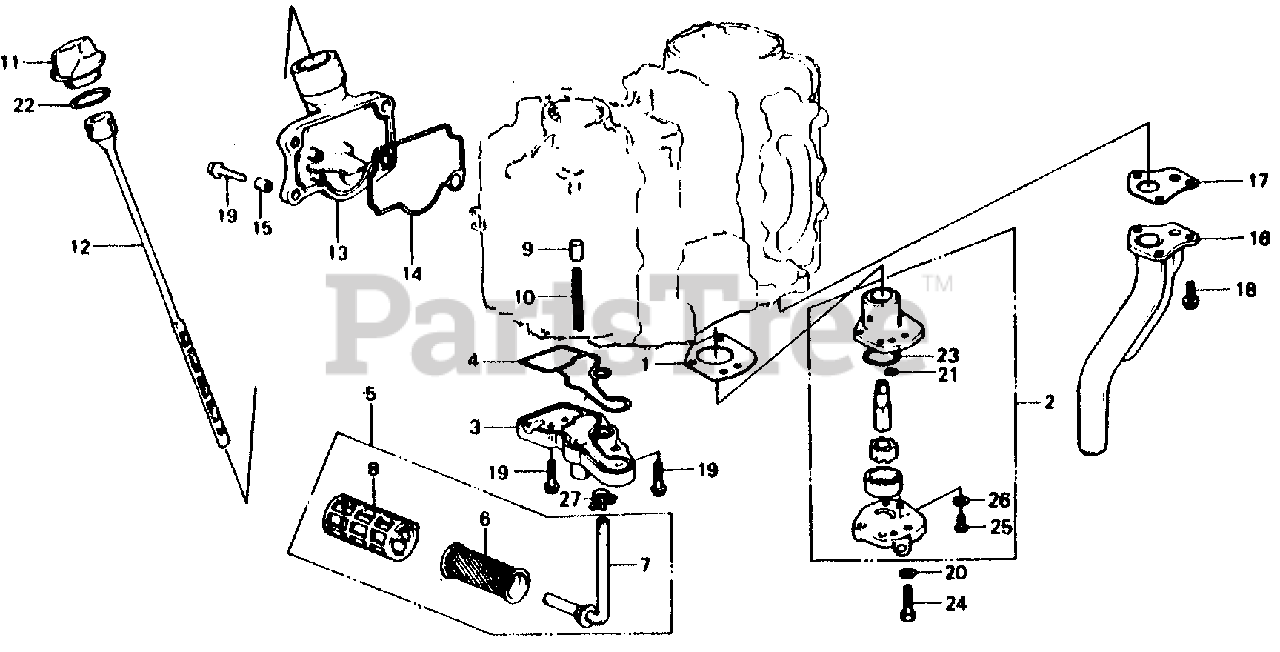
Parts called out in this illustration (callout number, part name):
1	GASKET, PUMP BODY
2	PUMP ASSY., OIL
3	FLANGE, OIL FILTER
4	GASKET, OIL FILTER
5	FILTER ASSY., OIL (NOT AVAILABLE)
6	FILTER, OIL
7	TUBE, OIL (NOT AVAILABLE)
8	HOLDER, OIL FILTER
9	VALVE, CHECK
10	SPRING, CHECK VALVE
11	CAP, OIL (YELLOW)
12	DIPSTICK, OIL
13	BODY, OIL FILTER
13	BODY, OIL FILLER
14	GASKET, OIL FILLER BODY
15	COLLAR A, DISTANCE
17	GASKET, EX. PIPE
18	BOLT, FLANGE (6X16)
19	BOLT, FLANGE (6X22)
20	WASHER A (6MM)
21	O-RING (6.8X1.9)
22	O-RING (26X2.7)
23	O-RING (25X1.0)
24	BOLT, HEX. (6X28)
25	SCREW, PAN (5X10)
26	WASHER, PLAIN (5MM)
27	CLIP, TUBE (A12)
